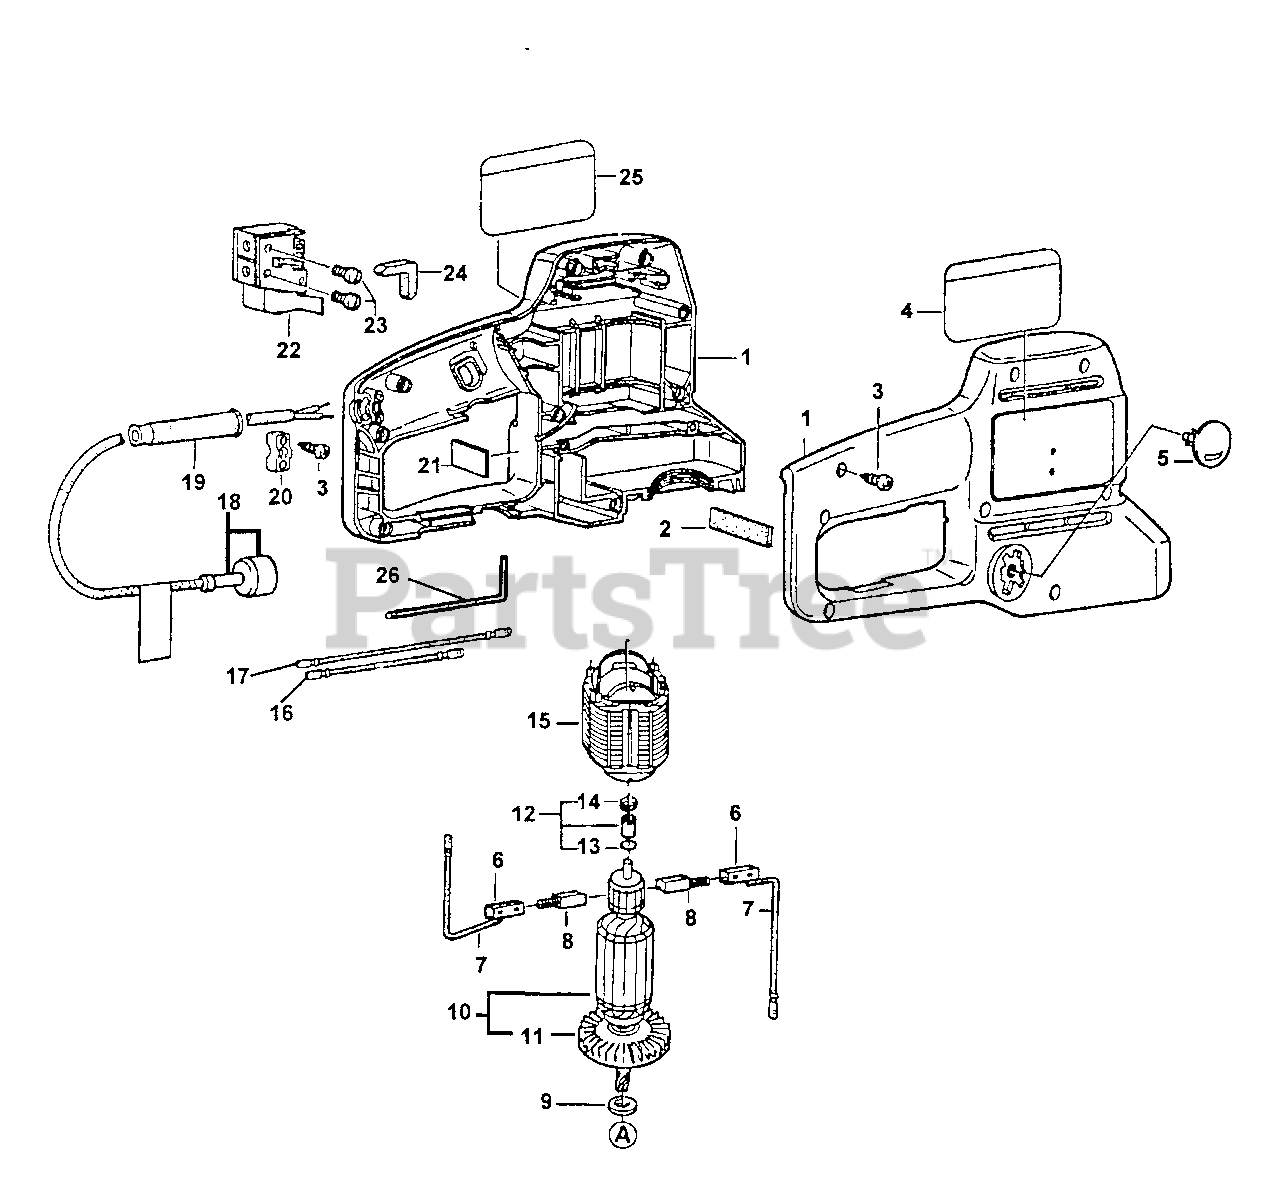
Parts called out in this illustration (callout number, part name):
1	HOUSING, MOTOR
2	SEAT, FELT
3	SCREW - 4X16
4	LABEL - ECHO 2000
5	KNOB
6	HOLDER, BRUSH
7	CABLE - 80mm
8	BRUSH SET
10	ARMATURE - 115V
11	FAN
12	BUMPER ASSY
13	SEAL, FELT
14	O-RING
15	FIELD 115V
16	CABLE - 100mm
17	CABLE - 200mm
18	CORD (115V)
19	RELIEF, STRAIN
20	CLAMP, CORD
21	LABEL - WARNING
22	SWITCH, IGNITION
23	SCREW
24	STRIP, SEAL
25	LABEL - MODEL EHC-3000
26	HEX KEY
